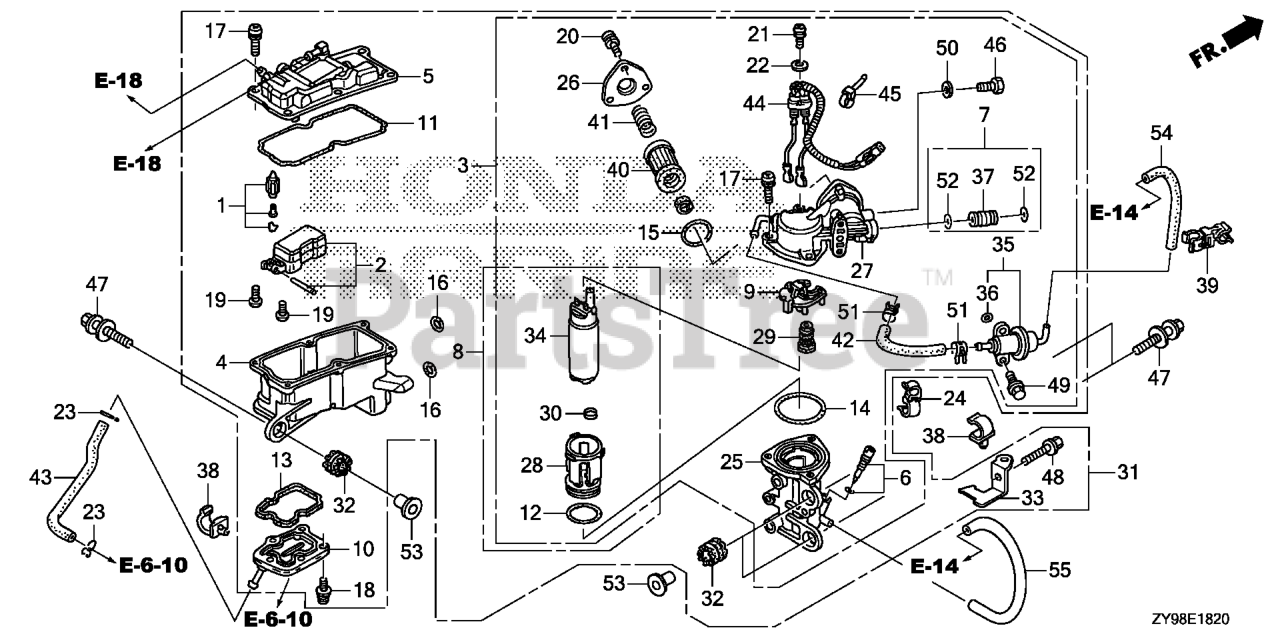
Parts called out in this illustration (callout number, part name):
1	VALVE SET, FLOAT
3	PUMP UNIT SET
6	SCREW SET, DRAIN (CARBURETOR NO.)
8	PUMP UNIT, FUEL (B) (MSDS)
10	COVER, WATER JACKET
17	SCREW-WASHER
18	SCREW-WASHER
19	SCREW, PAN
20	SCREW-WASHER
21	SCREW, WASHER
22	WASHER, PLAIN
23	CLIP, TUBE (ENGINE NO.)
24	CLAMP, CHECK VALVE
25	CASE, PUMP
26	COVER B, PUMP
27	COVER, PUMP (A)
29	INSULATOR
31	VAPOR SEPARATOR
32	GROMMET, VAPOR SEPARATOR
33	STAY, FUEL TUBE
34	PUMP UNIT, FUEL (MSDS)
35	REGULATOR ASSY., PRESSURE
36	O-RING, PRESSURE REGULATOR
37	JOINT, FUEL PIPE
38	CLAMP B, FUEL TUBE
39	CLAMP D, FUEL TUBE
40	SCREEN, FUEL STRAINER
41	SPRING, COMPRESSION
42	HOSE, PRESSURE REGULATOR RETURN
43	TUBE A, WATER
46	BOLT, SEALING (6MM)
47	BOLT-WASHER (8X35)
48	BOLT, FLANGE (6X25)
49	BOLT, FLANGE (6X14)
50	WASHER, SEALING (6MM)
51	CLAMP, TUBE (D10.7)
52	O-RING (7.8X1.9) (ARAI)
53	COLLAR (8.5X14.5)
54	BULK HOSE, FUEL (3.5X3000) (3.5X120)
55	BULK HOSE, VINYL (5X9X1000) (5X9X240)
